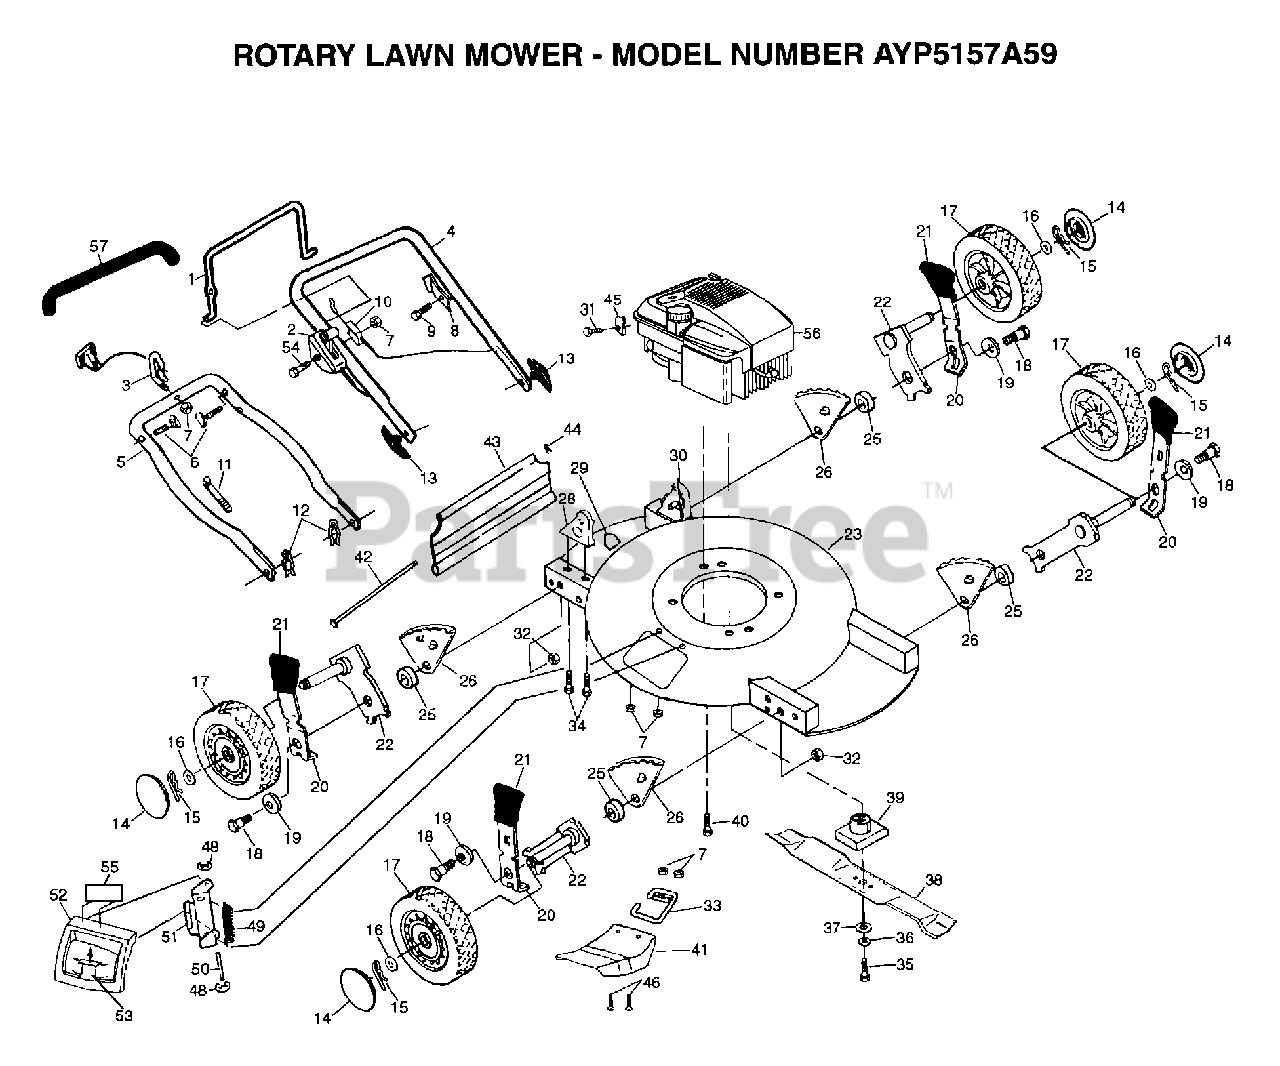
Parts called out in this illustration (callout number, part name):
1	CONTROL BAR PM
2	CONTROL.THL.49.35
3	ROPER GUIDE PM
6	BOLT.HANDLE.LM
8	"BRKT,UPSTOP"
9	TAPPING SCREW
10	"CABLE,ENG ZONE CO"
12	HAIRPIN COTTER
13	KNOB HANDLE
14	HUB CAP
15	RETAINER CLIP PM
16	WASHER
18	BOLT SHLD 3/8-16
19	"WASHER, BELLEVIL."
20	SPRING SELECTOR
21	KNOB PM
22	AXLE ARM
23	KIT HSG 20 CONV
26	BRACKET.ADJ.9POS.
29	DECAL-DANGER PM
31	SCREW PM
32	LOCKNUT PM
33	BRACKET.CHUTE.MTG
34	SCREW
35	SCREW
36	LOCKWASHER
37	"WASHER,HARDEN"
39	ADAPTOR.BLADE.LM
40	SCREW
41	"DEFL,MULCHER"
42	"ROD,DEFLEC PM"
43	SKIRT.REAR.20MULC
44	RETAINER CLIP
45	CABLE CLAMP
48	E-RING
49	SPRING PM
52	DOOR MULCHER
53	LATCH MUL DOOR
54	SCREW.HXHD.WASH.
55	DECAL.CHUTE.MULCH
